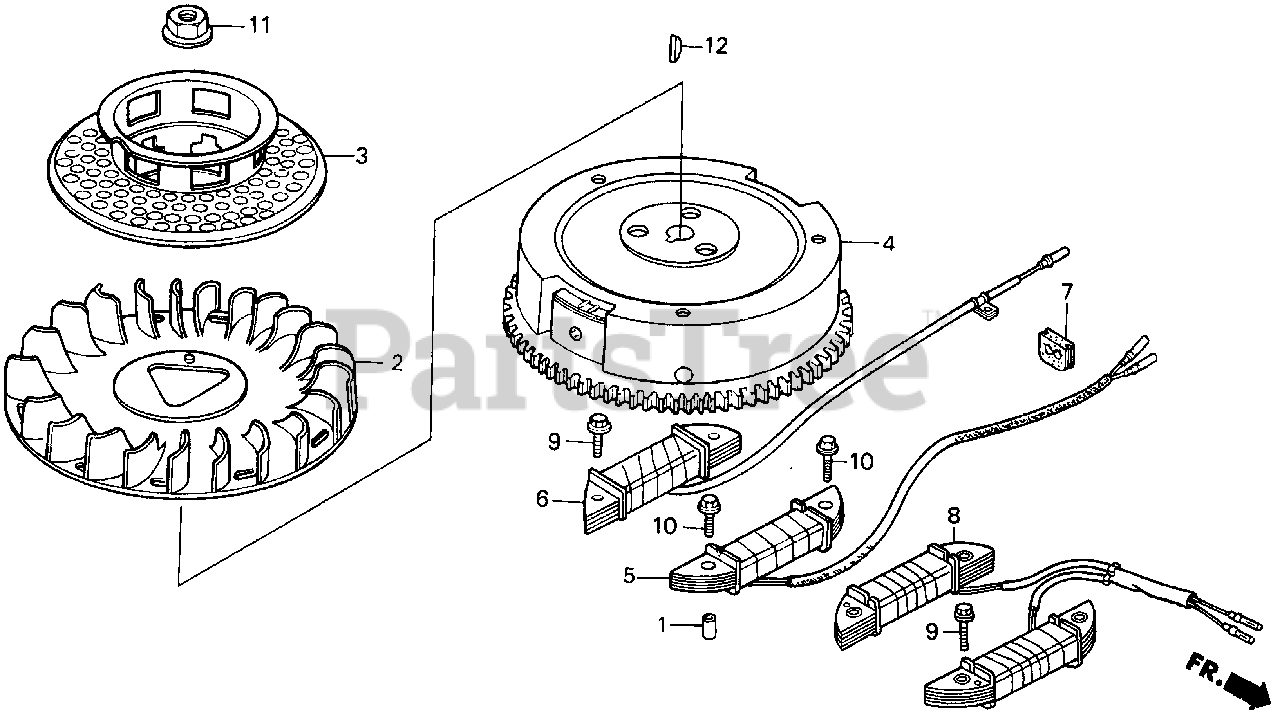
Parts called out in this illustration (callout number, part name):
1	COLLAR, EXTENSION
2	FAN, COOLING
4	FLYWHEEL
5	COIL ASSY., CHARGE
7	GROMMET, WIRE
10	BOLT, FLANGE (6X28)
10	BOLT, FLANGE (6X25)
11	NUT, SPECIAL (16MM)
12	KEY, SPECIAL WOODRUFF (25X18)
